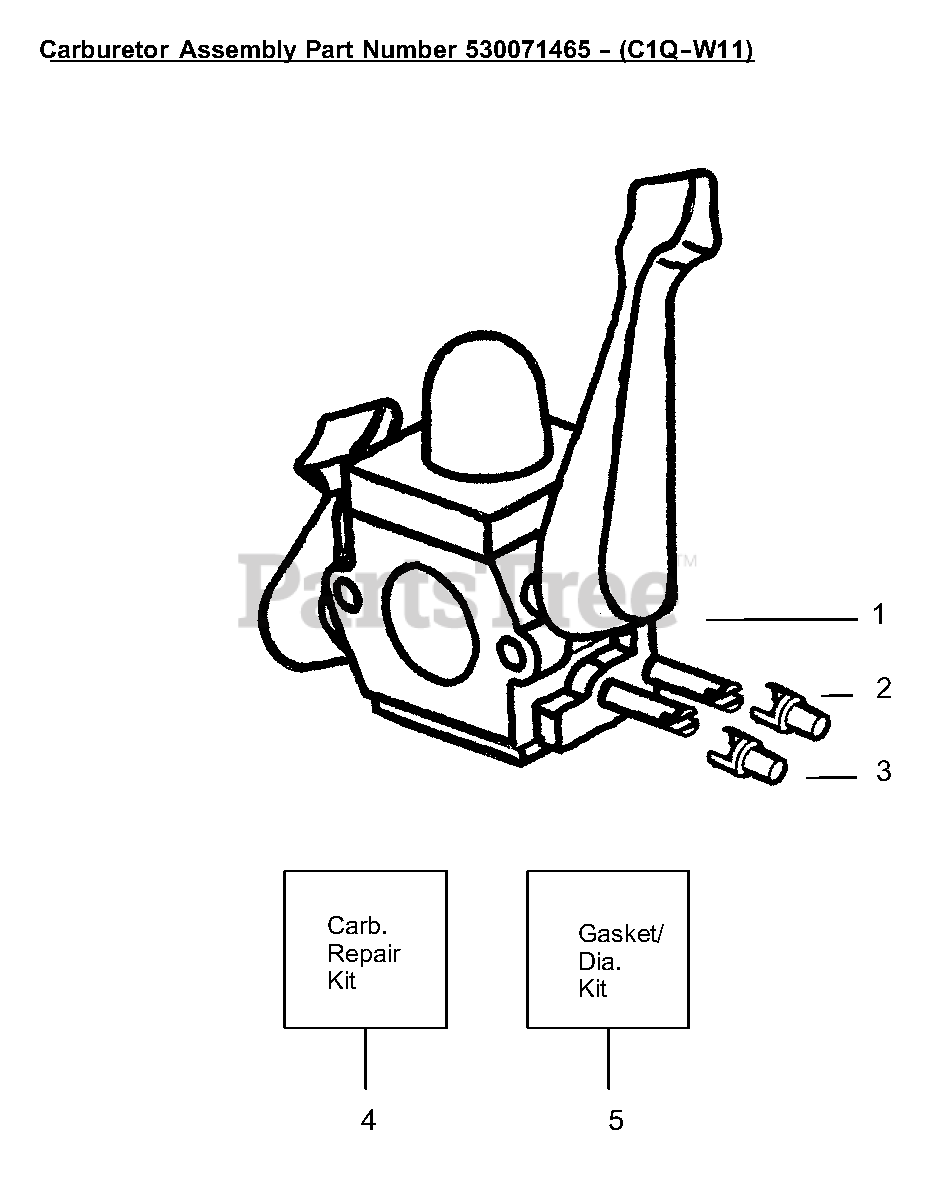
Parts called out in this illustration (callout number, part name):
1	Assy-Carb. Zama (C1Q-W11)
2	Cap-Limiter (high) brown
3	Cap-Limiter (low) tan
4	Kit-Carb. Repair
5	Kit-Dia. (GND-34)
